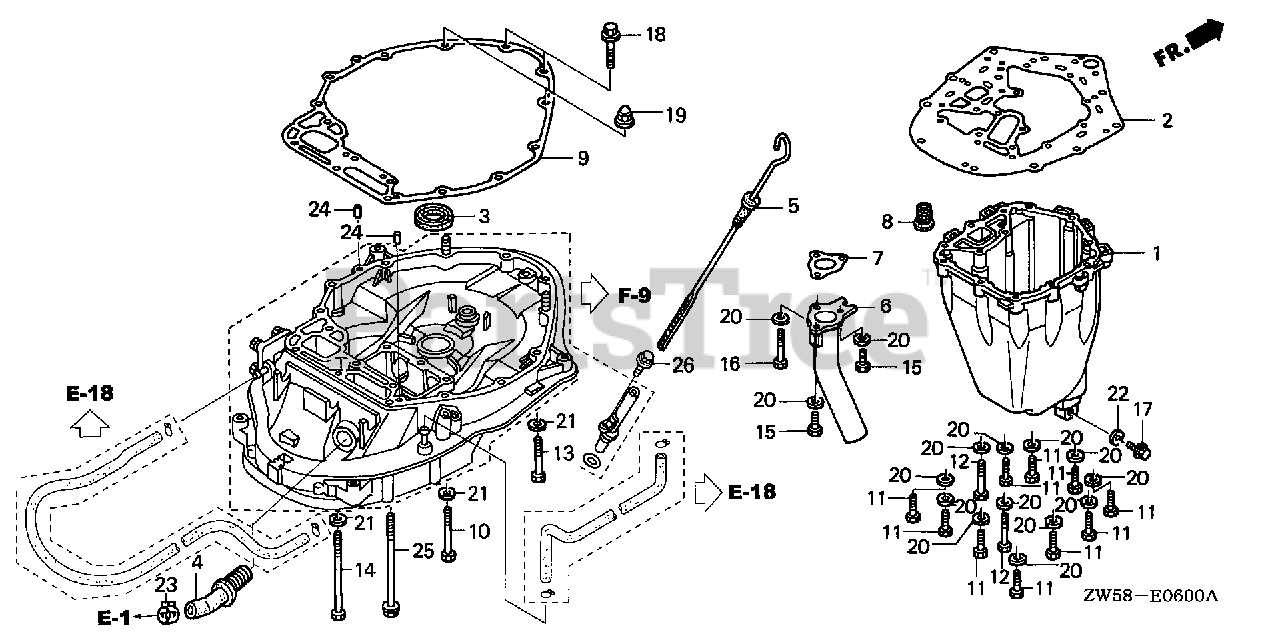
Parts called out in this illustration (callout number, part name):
1	PAN, OIL *TGRAY* (GRAY)
2	GASKET, OIL PAN
3	RUBBER, OIL PUMP
4	TUBE SET, OIL
5	DIPSTICK, OIL
7	GASKET, EX. PIPE
8	GROMMET, WATER TUBE
9	GASKET, MOUNT CASE
10	BOLT, HEX. (10X60)
11	BOLT, HEX. (8X35)
12	BOLT, HEX. (8X55)
13	BOLT, HEX. (10X47)
14	BOLT, HEX. (10X110)
15	BOLT, HEX. (8X25)
16	BOLT, HEX. (8X65)
17	BOLT, DRAIN PLUG
18	BOLT, FLANGE (10X45)
19	NUT, CAP (10MM)
20	WASHER, PLAIN (8MM)
21	WASHER, PLAIN (10MM)
22	WASHER, DRAIN PLUG (12MM)
23	CLAMP, TUBE (D29)
24	PIN, DOWEL (6X10)
25	BOLT, FLANGE (10X130)
26	BOLT, FLANGE (6X12)
